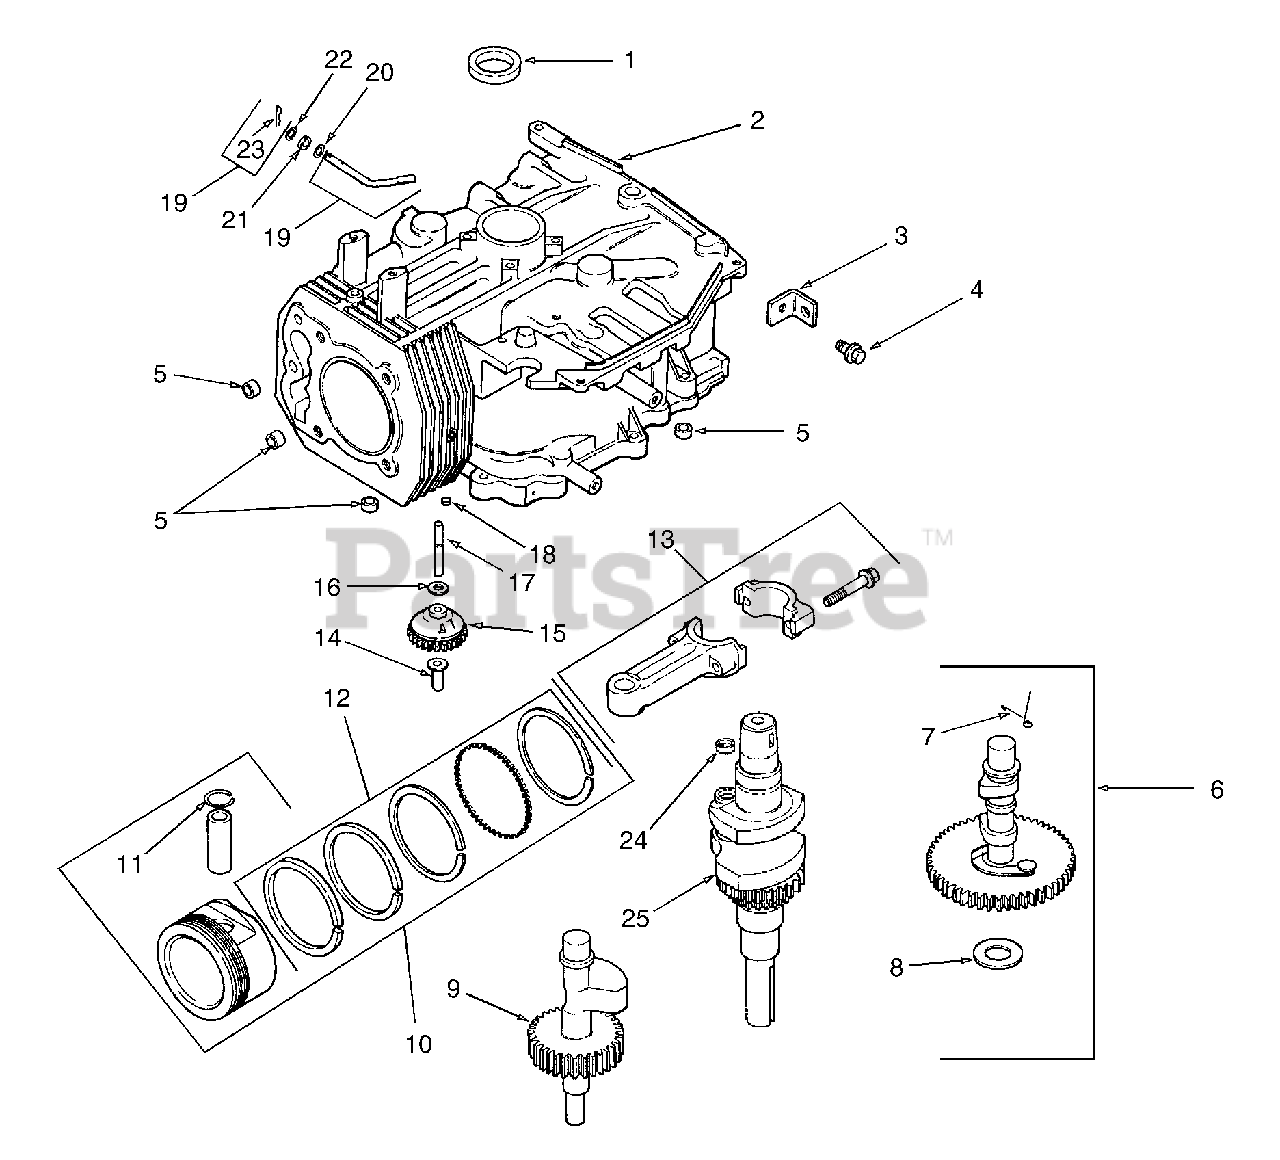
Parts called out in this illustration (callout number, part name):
1	Seal, Crankshaft Oil
2	Cylinder Block
3	Strap, Lifting
4	Screw, Hex Flange, M8 x 1.25 x 25
5	Dowal, Locating
6	Camshaft Kit
7	Spring, Actuating
8	Shim, Crankshaft, .032 (Red)
9	Shaft, Balance
10	Piston, w/Ring Set, Std
11	Retainer, Piston Pin
12	Ring Set, Std.
13	Rod Ass'y, Connecting, Std.
14	Pin, Governor Regulating
15	Gear Ass'y, Governor
16	Washer, Plain 6mm
17	Shaft, Governor Gear
18	Plug, Cup
19	Cross Shaft Kit, Governor
20	Washer, Plain 1/4
21	Seal, Governor Cross Shaft
22	Washer, Plain 6mm
23	Clip, Hitch Pin
25	Crankshaft
